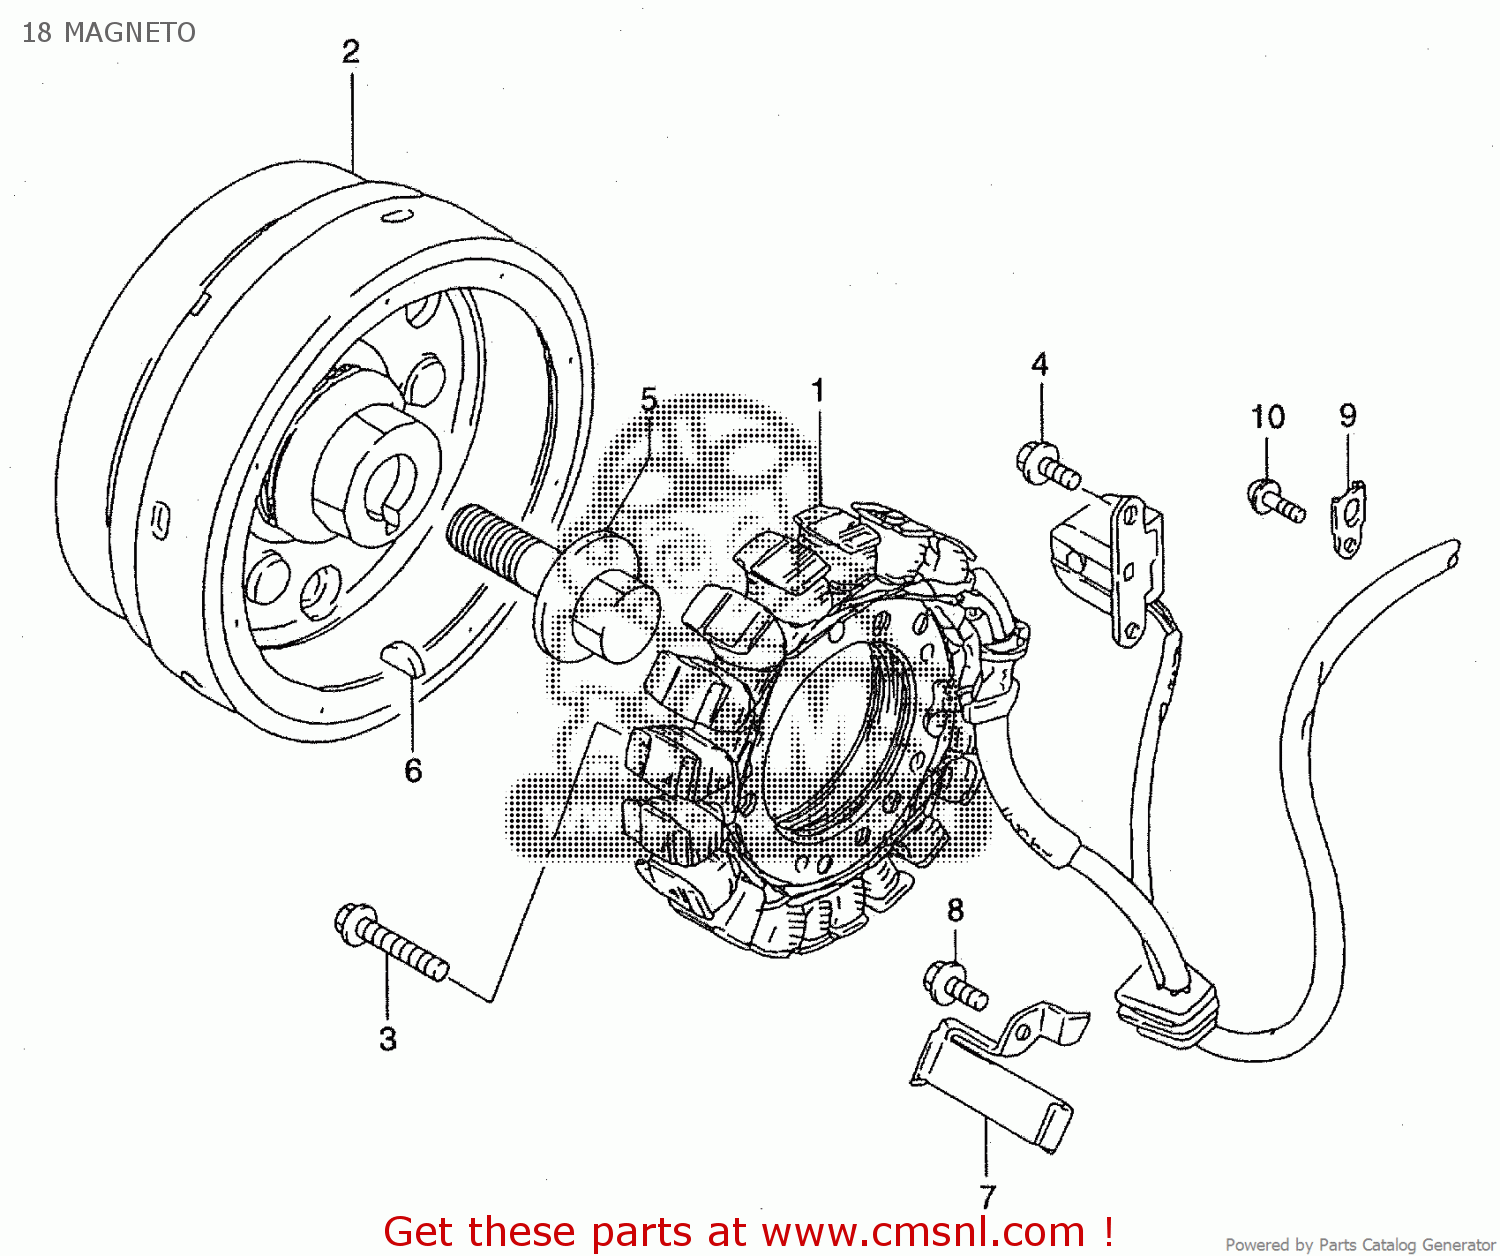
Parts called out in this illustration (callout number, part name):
1	STATOR ASSEMBLY
2	ROTOR ASSY
3	SCREW
4	BOLT
5	BOLT(14X43)
6	KEY
7	CLAMP,MAGNETO LEAD WIRE NO.1
8	BOLT
9	CLAMP,GENERATOR LEAD WIRE
10	SCREW
